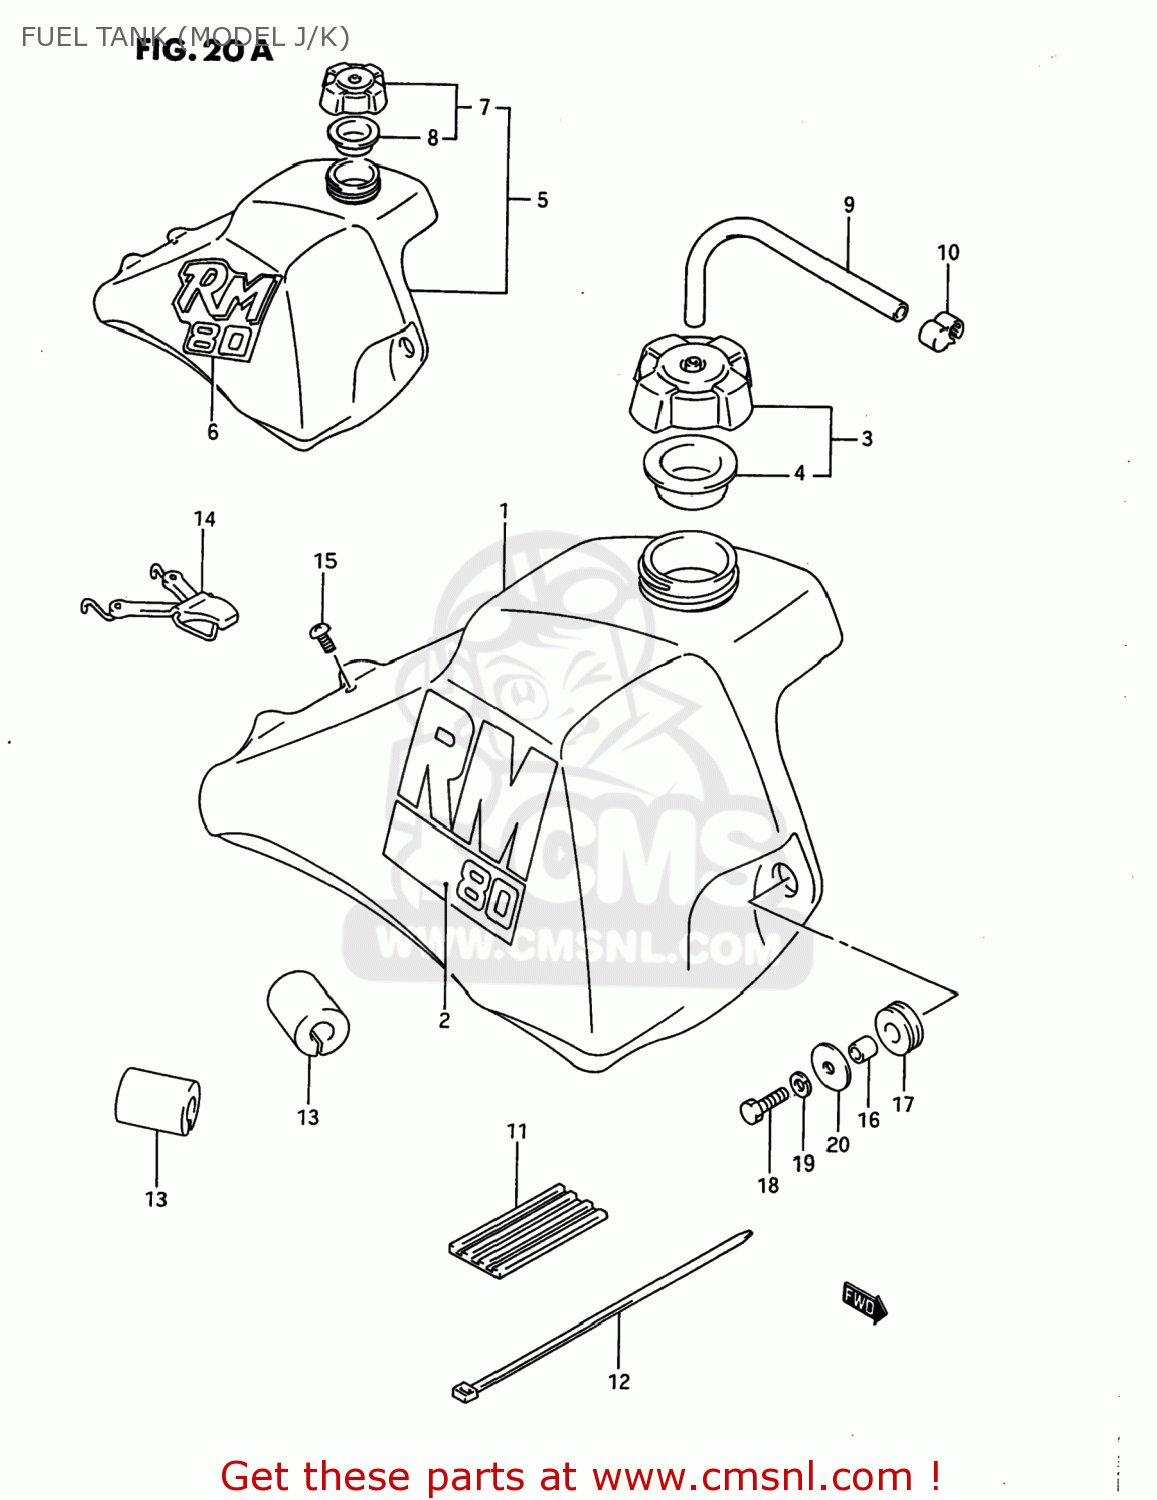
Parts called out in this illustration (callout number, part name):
1	TANK ASSEMBLY,FUEL
2	EMBLEM,FUEL TANK
3	CAP SET,FUEL TANK
4	GASKET,FUEL TANK CAP (NAS)
5	TANK ASSEMBLY,FUEL
6	EMBLEM,FUEL TANK
7	CAP SET,FUEL TANK
8	GASKET,FUEL TANK CAP (NAS)
9	HOSE
10	CLAMP,FUEL TANK BREATHER HOSE
11	CUSHION,FUEL TANK UPR FR
12	CLAMP
13	CUSHION,FUEL TANK UPR RR
14	BAND,FUEL TANK RR
15	SCREW
16	SPACER (6.8X10X11.5)
17	CUSHION
18	BOLT
19	WASHER,LOCK
20	WASHER (6.5X24X1.6)
